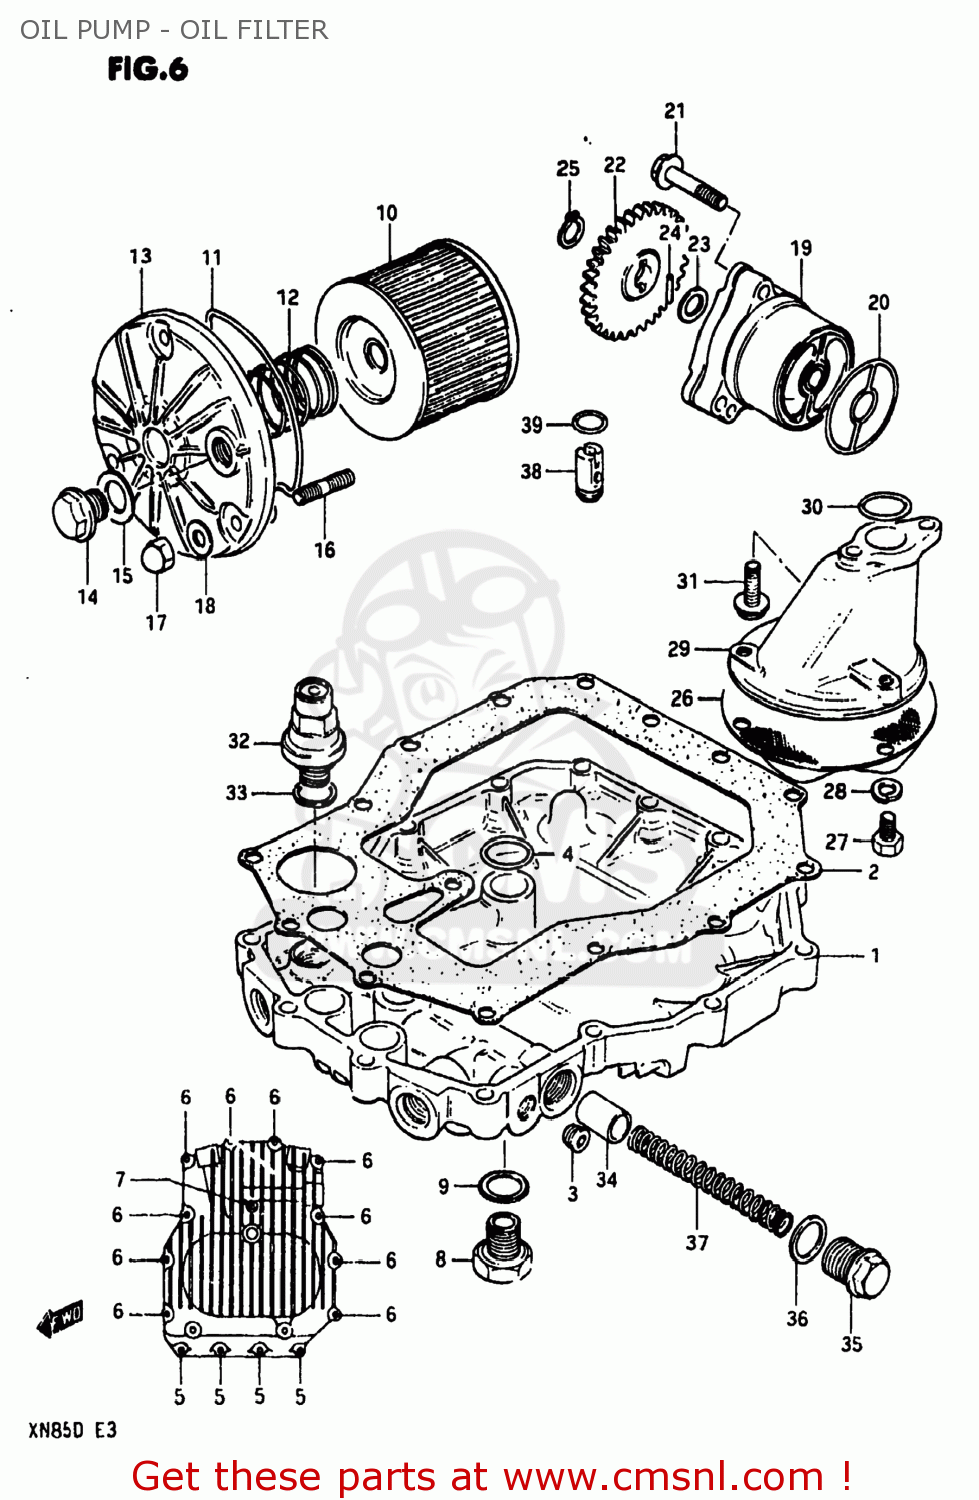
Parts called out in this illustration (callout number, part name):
1	PAN,OIL
2	GASKET,OIL PAN
3	PLUG
4	O RING(D:3.2,ID:17.8)
5	BOLT (6*25)
6	BOLT (6*30)
7	BOLT (6*35)
8	PLUG (14X12)
9	GASKET(14X19.2X2) (NAS)
10	FILTER ASSY,ENGINE OIL
11	O RING,OIL FILTER CHAMBER CAP
12	SPRING
13	CAP,OIL FILTER
14	PLUG (14X12)
15	GASKET(14X19.2X2) (NAS)
16	STUD 6X20
17	NUT
18	WASHER
19	PUMP ASSEMBLY,OIL
20	O-RING,OIL PUMP
21	BOLT
22	GEAR,ENG OIL PUMP DRIVEN(NT:33
23	SHIM
24	PIN(4X15.8)
25	CIRCLIP
26	STRAINER,ENGINE OIL
27	BOLT
28	LOCK WASHER
29	PROTECTOR,OIL STRAINER
30	O RING(D:3.2,ID:17.8)
31	BOLT,REAR
32	REGULATOR ASSY,ENGINE OIL
33	WASHER
34	PLUNGER,CONTROL
35	PLUG
36	GASKET(16X22X2) (NAS)
37	SPRING
38	VALVE ASSEMBLY,PISTON OIL
39	O RING(D:1.3,ID:9.8)
